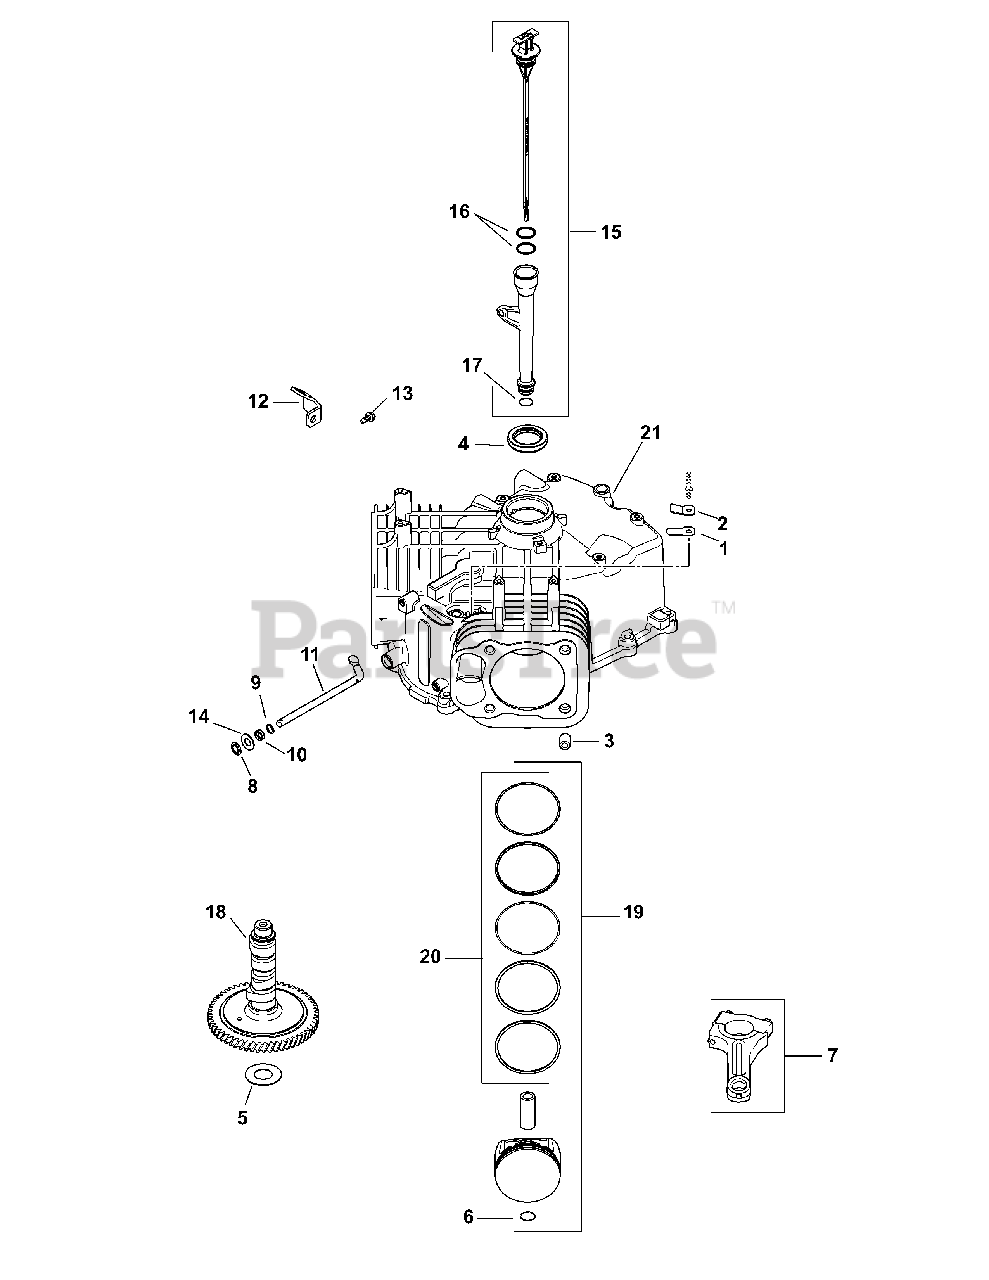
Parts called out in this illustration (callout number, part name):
1	Breather Reed
2	Breather Reed Retainer
4	Oil Seal, 1.78 x 1.26
5	Camshaft Shim (White, .028)
5	Camshaft Shim (Blue, .03)
5	Camshaft Shim (Red, .032)
5	Camshaft Shim (Yellow, .034)
5	Camshaft Shim (Green, .036)
5	Camshaft Shim (Gray, .038)
5	Camshaft Shim (Black, .04)
6	Piston Pin Retainer
7	Connecting Rod (STD)
8	Ring Retainer
9	Flat Washer, 11/32
10	Governor Cross Shaft Seal
11	Governor Cross Shaft
12	Oil Fill Tube Bracket
13	Flange Screw, M5 x .8 x 13
14	Flat Washer, 9mm
15	Dipstick & Tube Kit
17	Lower Oil Fill Tube O-Ring
18	Camshaft Assembly
19	Piston W/ Ring Kit (STD)
19	Piston W/ Ring Kit (0.25) 83mm
19	Piston W/ Ring Kit (0.08) 83mm
20	Ring Set (STD)
20	Ring Set (.08)
20	Ring Set (.25)
21	Crankcase (Use Short Block)
